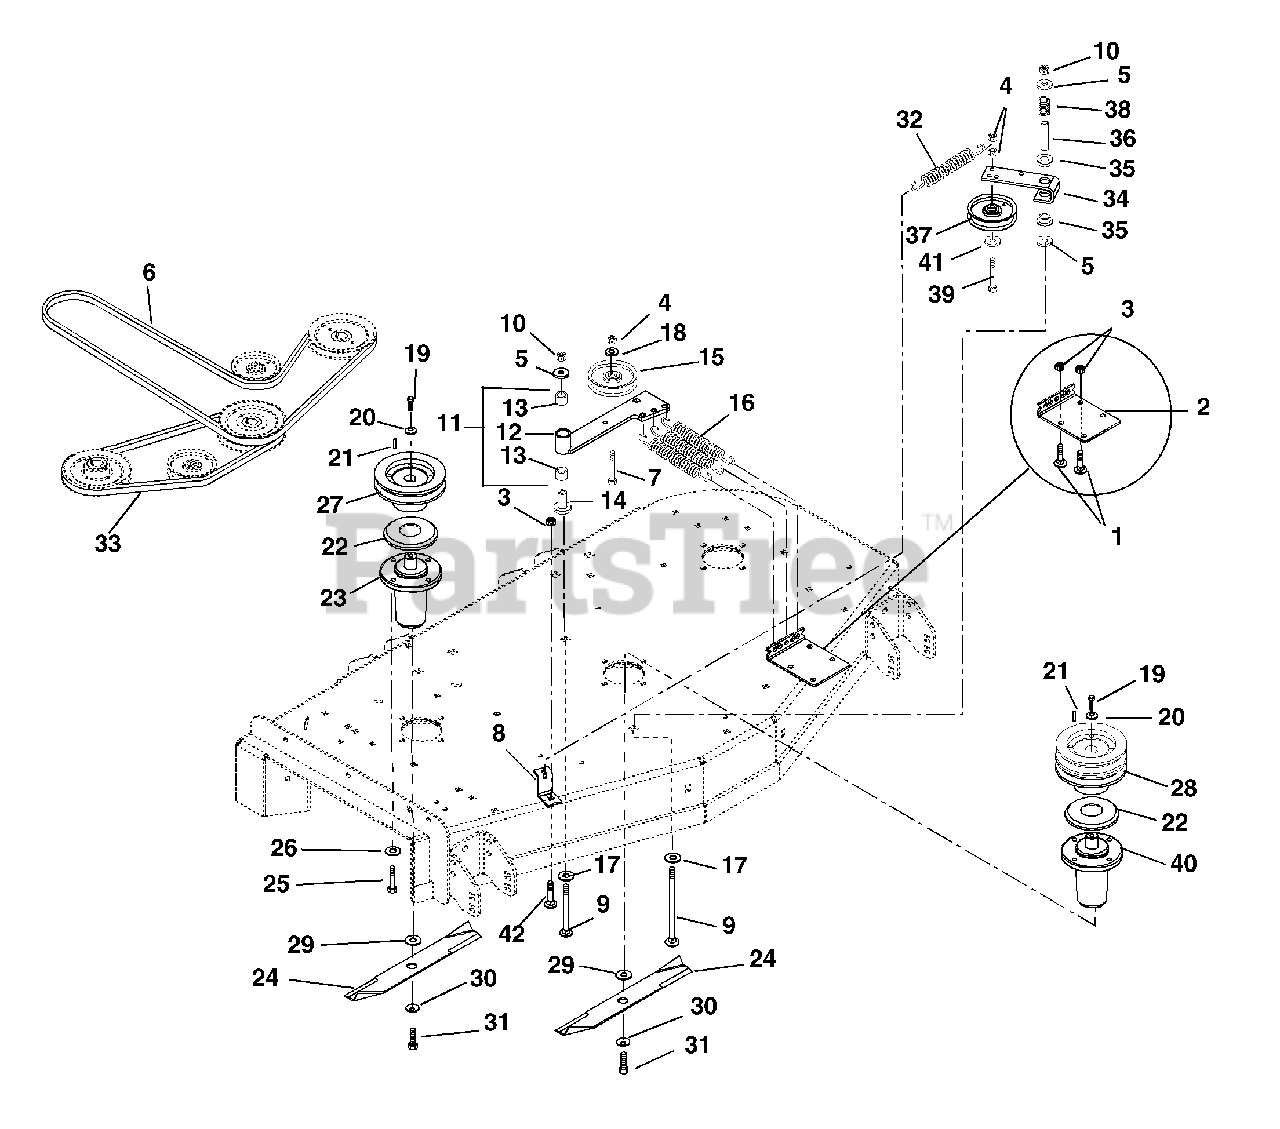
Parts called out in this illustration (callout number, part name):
1	@BLT-RDHDSQNK .38-16X.75 G5YZ
2	BRACKET,LONG SPRING (DIESEL)
3	@NUT-LK-TOP-FLG .38-16 YWZC
4	@NUT-LK-CTR .38-16 YWZC
5	@WSHR-FL-STL.50X1.25X.083 YWZC
6	V-BELT, HB-WRAPPED
7	@BLT-RDHDSQNK .38-16X2.75 G5YZ
8	ANCHOR, SPRING (RED)
9	@BLT-RDHDSQNK .50-13X3.50 G5YZ
10	@NUT-LK-TOP-FLG .50-13 YWZC
11	ASSY-DECK IDLER PIVOT ARM
12	WMT, DECK IDLER PIVOT ARM
13	BRG, 1.00 X 1.12 X .75
14	BEARING, PEDESTAL
15	IDLER-FLAT 4.00 X .38 (2.32W)
16	SPRING, EXT0NSION DIA1.0X6.0LG
17	WSHR-FL-STL.755X1.375X.062YWZC
18	WSHR-FL-STL .375X1.125X.065YWZ
19	BLT-HEX .38-16X1.00 YZ GR8
20	WASHER, CUPPED SERRATED, .375
21	KEY, SQ .25X.25X1.00 RC 40-50
22	SLINGER, DUST
23	ASM,MAINT FREE SPINDLE
24	BLADE 60" MOWER CE
24	BLADE, MULCHING (20.50")
25	@BLT-HEX .38-16X1.00 GR5 YWZC
26	@WSHR-LK .38X.094 REG YWZC
27	WELDMENT, SPINDLE SHEAVE 6.00
28	SHEAVE, DOUBLE (6.25")
29	WSHR-FLT .640X1.75X.250 YWZC
30	WSHR-BLVL .669X1.535X.138
31	BLT-HEX .62-18X1.75 GR8 YWZC
32	SPRING, EXT
33	V-BELT, HB-RAW EDGE
34	ARM,IDLER PIVOT
35	BSHG-FLG .762X1.0X.580X1.48 NY
36	SPACER .560X.750X2.437 ST
37	V-IDLER, 4.00X.38
38	SG-COMP .085X.80X1.00 WLD36
39	@BLT-HEX .38-16X2.25 GR5 YWZC
40	ASM,MAINT FREE SPINDLE
41	@WSHR-FL-STL.406X.812X.065 YWZ
42	@BLT-RDHDSQNK .38-16X1.00 G5YZ
